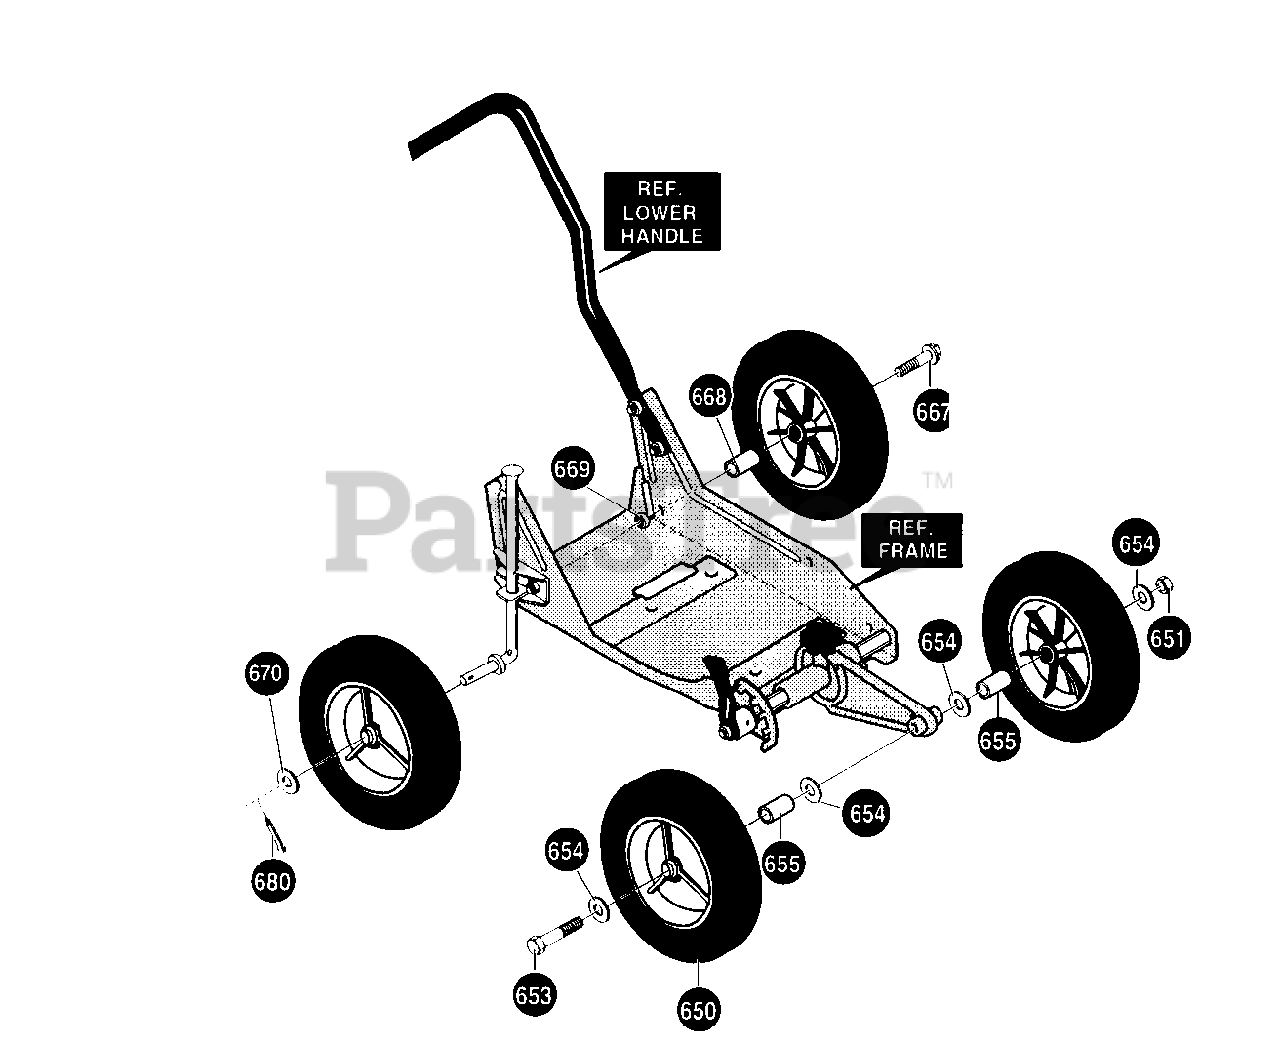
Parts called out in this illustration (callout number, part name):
650	Tire & Rim w/Brg 8 x 1.75
651	Nut, 5/16-18 Wdfllk
653	Screw, 5/16-18 x 4.50
654	Flatwasher, .344 x .69 x .065
655	Spacer, Slev .328 x .495 x 1.39
667	Shoulder Bolt, 3/8-16
668	Spacer, Slev .390 x .70 x .70
669	Nut, 3/8-16 Whiz-lock
670	Flatwasher .504 x .75 x .059
680	Cotter Pin .090 Dia x .75Lg
